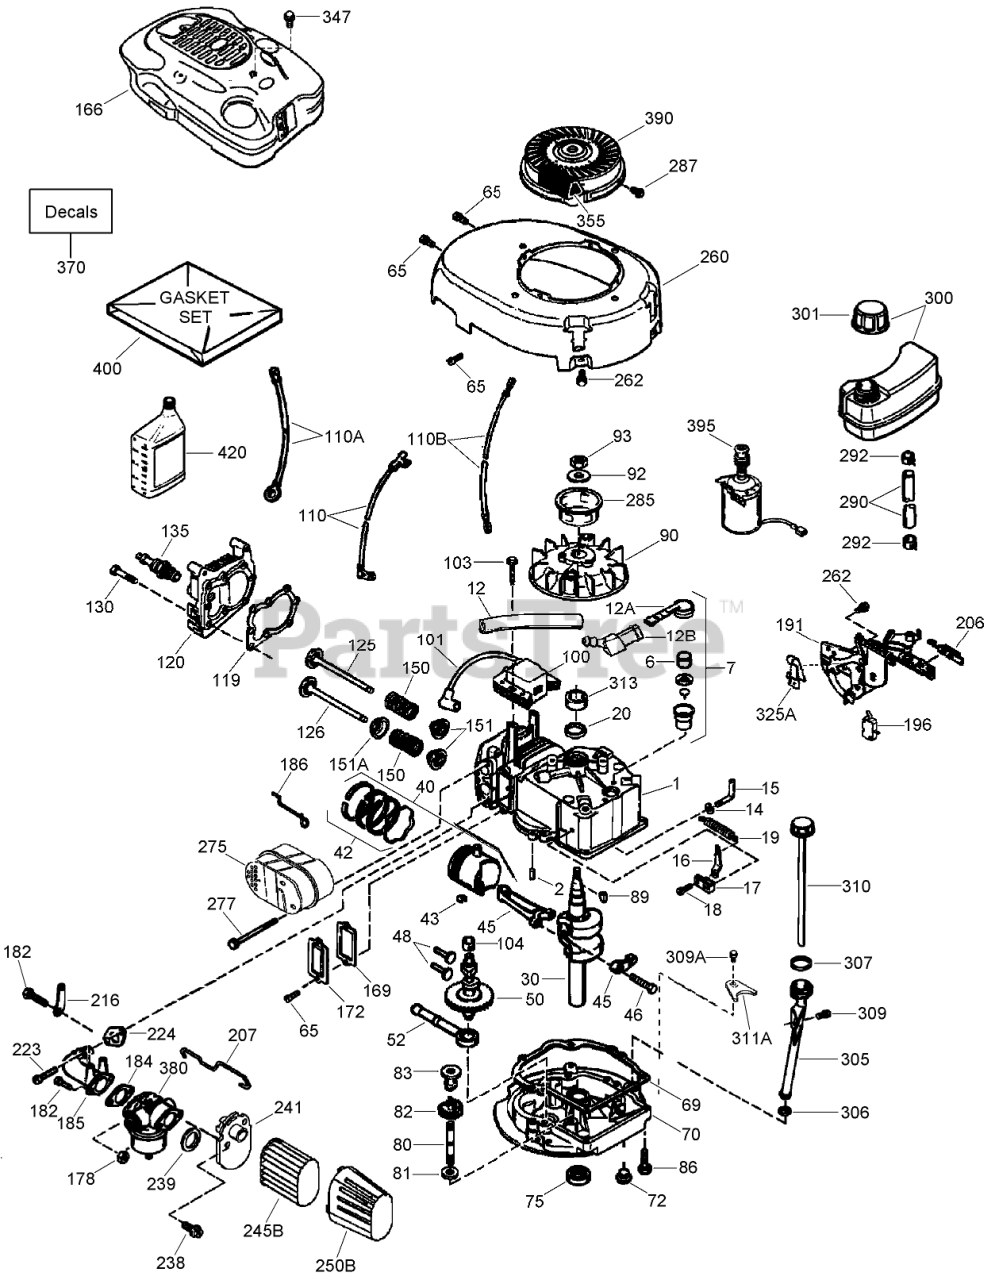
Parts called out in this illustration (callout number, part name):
150	Spring-Valve
151	Cap-Valve, Spring
151A	Seal-Valve, Intake
166	Shroud-Engine
169	Gasket-Cover, Valve
172	Cover-Valve
178	Nut and Lock Washer (1/4-28)
182	Screw (1/4-28 x 7/8)
184	Gasket
185	Pipe-Intake
186	Link-Governor
191	Bracket-Brake
196	Switch-Restart, Power
206	Terminal
207	Link-Throttle
216	Lever-Adjusting, R P M
223	Screw (1/4-20 x 1)
224	Gasket-Pipe, Intake
238	Screw (10-32 x 49/64)
239	Gasket-Cleaner, Air
241	Collar-Cleaner, Air
245B	Filter-Air Cleaner (Paper)
250B	Cover-Cleaner, Air
260	Housing-Blower
262	Screw (1/4-20 x 1/2)
275	Muffler
277	Screw (1/4-20 x 2-9/32)
285	Cup-Starter
287	Screw (8-32 x 21/64)
290	Line-Fuel, Low Permeation (8.62)
292	Clamp-Line, Fuel
300	Fuel Tank ASM (Includes 292, 301)
301	Cap-Fuel (Black) (1-1/2 I D)
305	Tube-Fill, Oil
306	O-Ring
307	O-Ring
309	Screw (10-32 x 1/2)
309A	Screw (10-24 x 3/4)
310	Dipstick
311A	Bracket-Holddown
313	Spacer
325A	Clip-Actuator, Brake Switch
347	Screw (10-32 x 27/32)
355	Handle-Starter (Std)
370	Decal-Warning
370	Decal-Primer
380	Carburetor ASM (Includes 184)
390	Starter-Recoil
395	12 Volt Electric Starter Motor ASM
400	Gasket Set
420	Oil-Engine (4-Cycle SAE 30)
